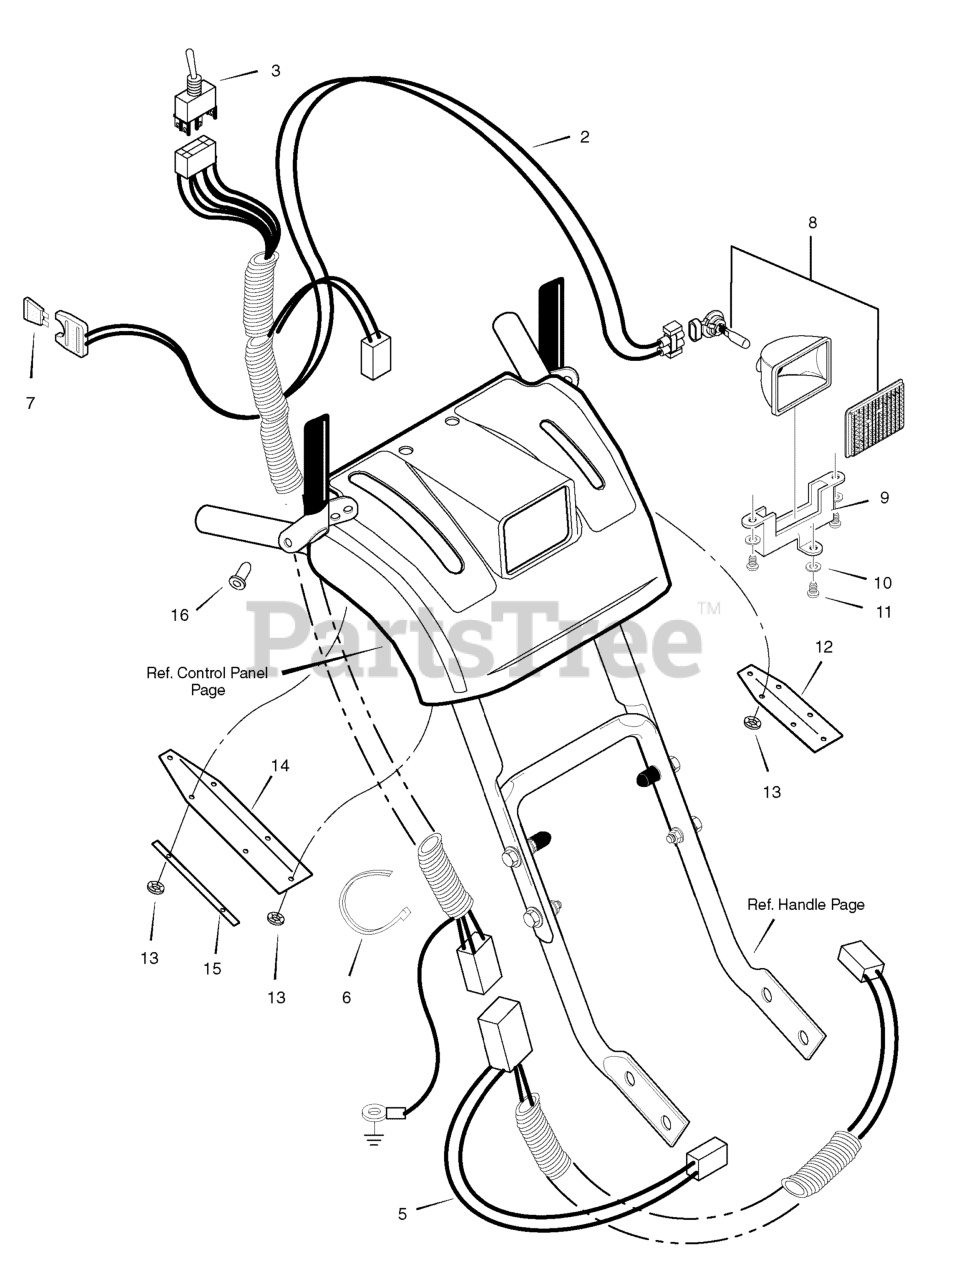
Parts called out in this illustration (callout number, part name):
2	HARNESS, UPPER WIRING
3	SWITCH, CHUTE ROTATION
5	HARNESS, LOWER WIRING
6	TIE, CABLE
7	FUSE, 7.5 AMP AUTOMOTIVE
8	ASSEMBLY, HEADLIGHT
9	BRACKET
10	WASHER, FLAT
11	SCREW #8 x .50
13	NUT, PUSH
16	RIVET, 0.125 x 0.23
